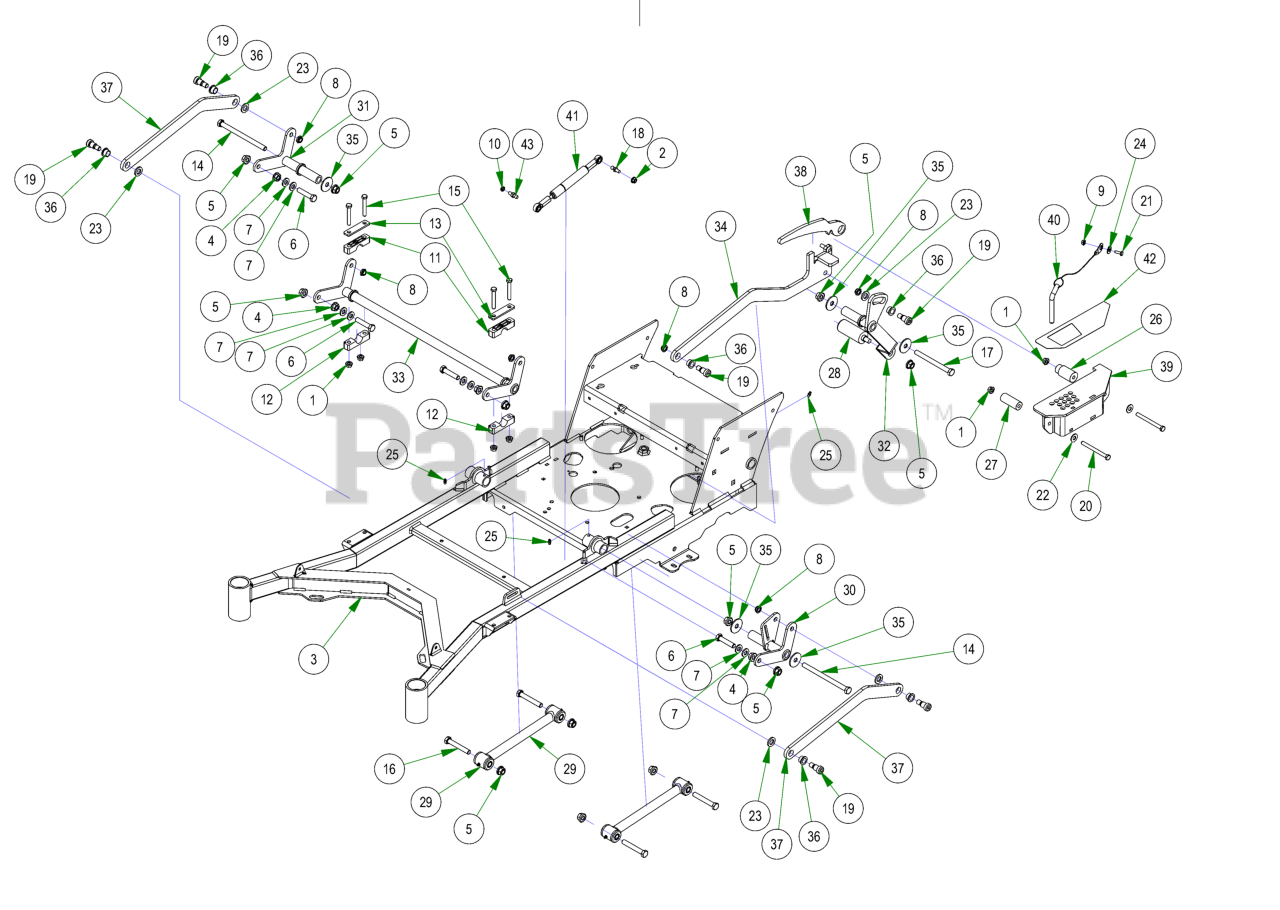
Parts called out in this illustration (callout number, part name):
1	3/8-16 NYLON INSERT FLANGE LOCKNUT (GR.F) ZINC
2	5/16-18 NYLON INSERT FLANGE LOCKNUT ZINC
3	2023 Walk Frame
4	1/2-13 HEX SERRATED FLANGE NUT HARD/ZINC
5	1/2-13 NYLON INSERT FLANGE LOCKNUT ZINC
6	1/2-13 X 2-1/4 HEX CAP SCREW (GR.5) ZINC
7	.505 ID X 1.000 OD X .125 THICK FLAT WASHER NYLON
8	1/2-13 NYLON INSERT JAM LOCKNUT ZINC
9	1/4-20 NYL INSERT FLANGE LOCKNUT ZINC
10	5/16-18 NYLON INSERT JAM LOCKNUT ZINC
11	Pillow Block MZ
12	Pillow Block MZ female
13	Pillow Block Strap
14	1/2-13 X 7 HEX CAP SCREW (GR.5) ZINC
15	3/8-16 X 2-1/2 HEX CAP SCREW (GR.5) ZINC
16	1/2-13 X 3-1/4 HEX CAP SCREW (GR.5) ZINC
17	1/2-13 X 5 1/2 HEX CAP SCREW (GR.5) ZINC
18	10mm Damper Ball Stud-XP Linkage
19	5/8 X 5/8 SOCKET SHOULDER BOLT ZINC YELLOW
20	3/8-16 X 4 HEX CAP SCREW (GR.5) ZINC
21	1/4-20 X 3/4 HEX CAP SCREW (GR.5) ZINC
22	3/8 FLAT WASHER USS (1" OD) ZINC
23	.635 ID X 1.120 OD X .140 THICK FLAT WASHER NYLON
24	5/16 USS FLAT WASHER (7/8 OD) ZINC
25	1/4 DRIVE-TYPE STRAIGHT GREASE FITTING (NO BALL) ZINC YELLOW
26	Stand On Spacer 2.5'' With shoulder
27	Stand On Spacer 2.5''
28	Knurled Pedal
29	Hybrid Turnbuckle/Deck Locator
30	23WB Right Rear Actuator
31	23WB Left Rear Actuator
32	23WB Foot Pivot weldment
33	23WB Actuator bar
34	23WB Deck Height Lever weldment
35	.520 ID X 1.750 OD X .120 THICK FLAT WASHER ZINC
36	.627 ID X .753 OD X .500 LGTH X 1.000 FLG OD X .094 FLG THICK FLANGED BEARING OIL-IMPREG BRNZ
37	23WB Actuator link V
38	23WB Deck Lever Lock V2
39	23WB deck height indicator weldment V3 4.27
40	2023 stand on Height Adj Pin
41	200 lb Gas Spring- 54" Deck outlaw
42	2023 WB Deck Height Decal
43	10mm Damper Ball Stud-Steering
